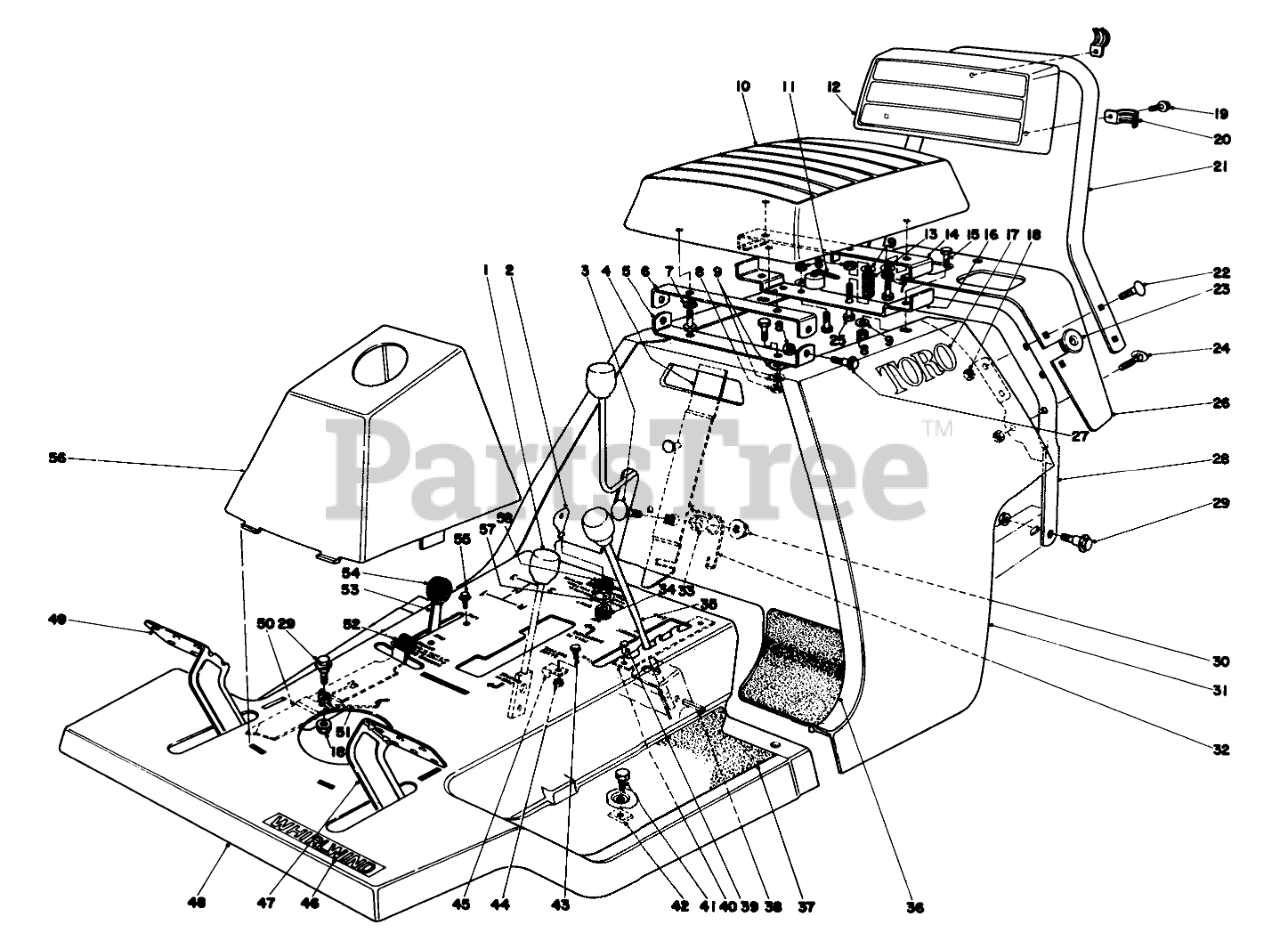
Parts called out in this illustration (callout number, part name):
3	BOLT-CARR
4	Handle Latch
5	Seat Pivot Brkt-Lower
6	Seat Pivot Brkt-Upper
7	WASHER-LOCK
8	NUT-LOCK, CONE
9	WASHER-FLAT
11	SEAT SWITCH
12	Backrest
13	Spring
14	Rear Support Seat
15	SCREW-HH
16	Seat Support Rear Lower
17	Decal
18	NUT-LOCK, CONE
19	SCREW-HHF
20	CLAMP-CONDUIT
21	Handle Upper
22	SCREW-CARR
23	Starting Ferrel
24	HANDLE SCREW
25	SCREW-HH
26	Extension Rear Body
27	SCREW-SHOULDER
28	Handle Lower
29	SCREW-SHOULDER
30	NUT-HF
31	Rear Body
32	Latch Return Spring
33	Spacer
34	ON-OFF SWITCH 21-8-468
35	Height of Cut Lever
36	Heel Pad-LH.
37	Foot Tread LH.
38	PIN-SPECIAL
40	Height Adjustment Plate
41	SCREW-HH
42	NUT-TINNERMAN
44	NUT-KEPS
45	CABLE CLAMP
46	WW DECAL
47	Clutch Pedal
48	Body Front (Incl. Ref. #39 & 40)
49	Brake Pedal
50	Parking Brake
51	SPRING-PARKING BRAKE
52	TIP-PARKING BRAKE
53	Throttle Control
55	8X1/2 SELF TAP SCREW
56	Tower
57	WASHER-TOOTH, INTERNAL
58	NUT-HH
